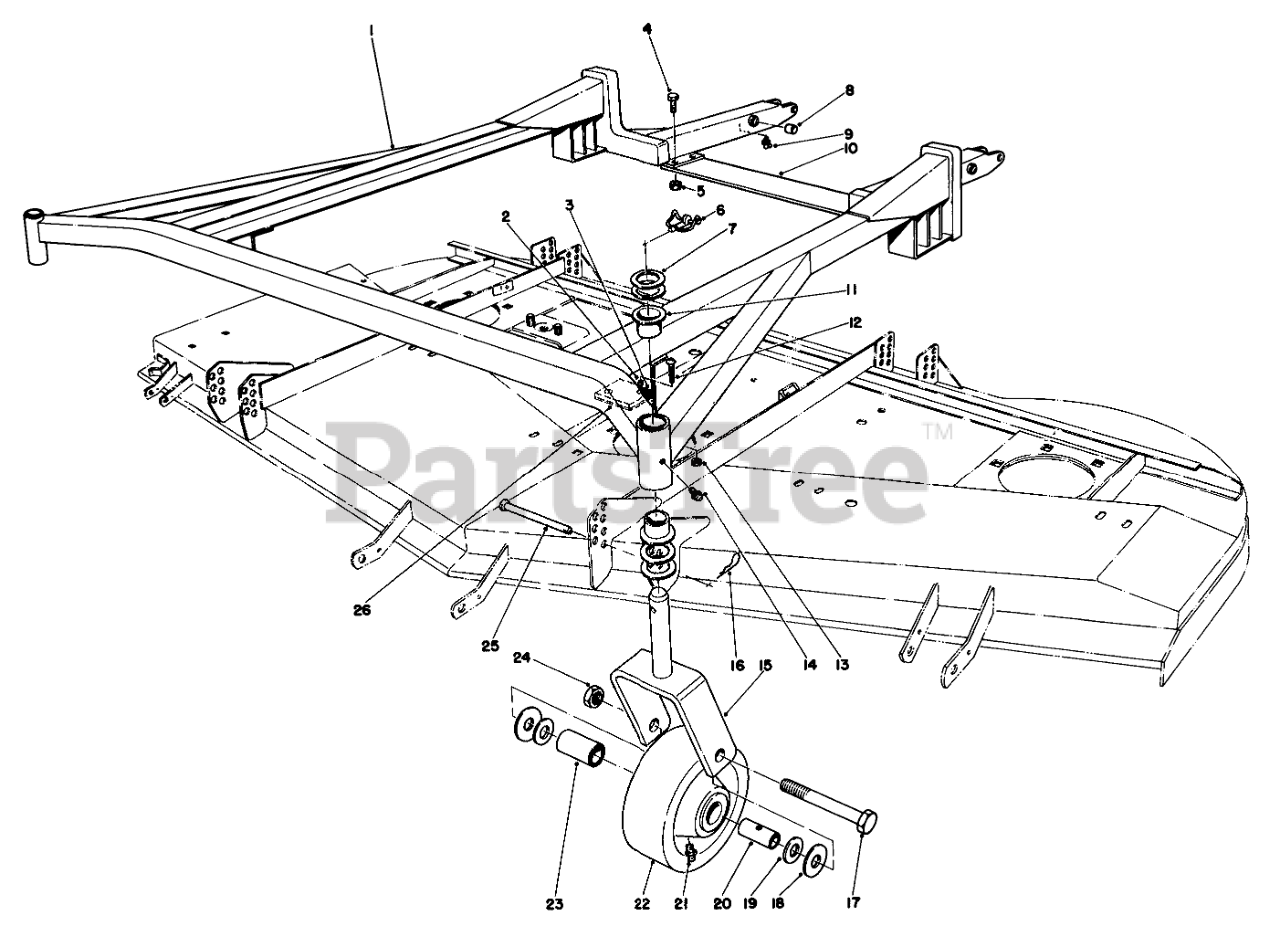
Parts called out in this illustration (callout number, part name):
1	Suspension Frame (Incl. Ref. #4-5, 8-10 & 11)
2	SPACER
3	CUSHION-RUBBER
4	SCREW-HH
5	NUT-LOCK, SIDE
6	PIN-LYNCH
7	WASHER-THRUST
8	7/8 ID X 1.128 X 7/8 LG BSHG
9	FITTING-GREASE, 90 DEG
10	Plate-Lift Arm
11	Bushing
12	SCREW
13	NUT-LOCK, NI
14	FITTING-GREASE
15	FORK-Castor
16	PIN-HAIR
17	SCREW-HH
18	THRUST WASHER
19	BEARING RETAINER
20	SPANNER BUSHING
21	FITTING-GREASE
22	Castor Wheel Assembly (Incl. Ref. #18-21 & 23)
23	ROLLER BEARING
24	NUT-LOCK
25	PIN-CLEVIS
26	SHIM-CUSHION
